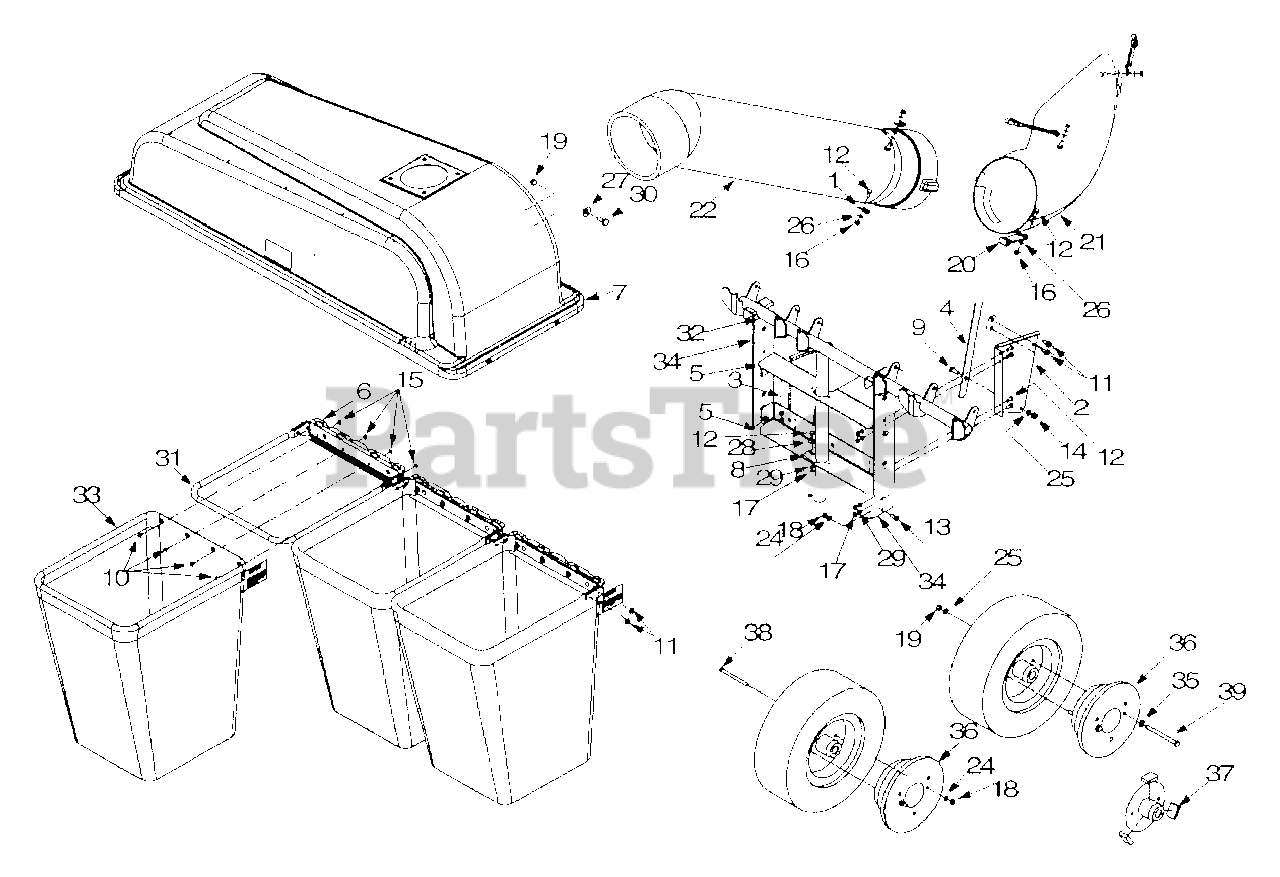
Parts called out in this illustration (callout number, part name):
1	Retainer Hook Bracket
7	Catcher Assembly: Cover
9	Hex Screw: 3/8-24 x .75" Gr.5
10	Machine Screw: 310-24 x 0.5"
11	TT Screw: 5/16-18 x 0.625"
12	Hex Screw: 1/4-20 x .620"
13	Hex Screw: 5/16-18 x .75"
14	Hex Nut: 3/8-24
15	Sems Nut: 10-24
16	Hex Lock Nut
17	Hex Nut: 1 /4-20
18	Hex Nut: 5/16-18
19	Hex Nut 3/8-16
20	Retainer Strap
21	Discharge Chute
22	Elbow Tube
24	Lock Washer
25	Lock Washer
26	Spring Washer
27	Bell Washer
28	Bell Washer
29	Lock Washer
30	Shoulder Screw
35	Flat Washer
36	Wheel Weight: 20 lb.
37	Foam Strip t
38	Hex Screw: 5/16-18 x 4" Gr.5
39	Hex Screw: 3/8-16 x 4 5" Gr.5
